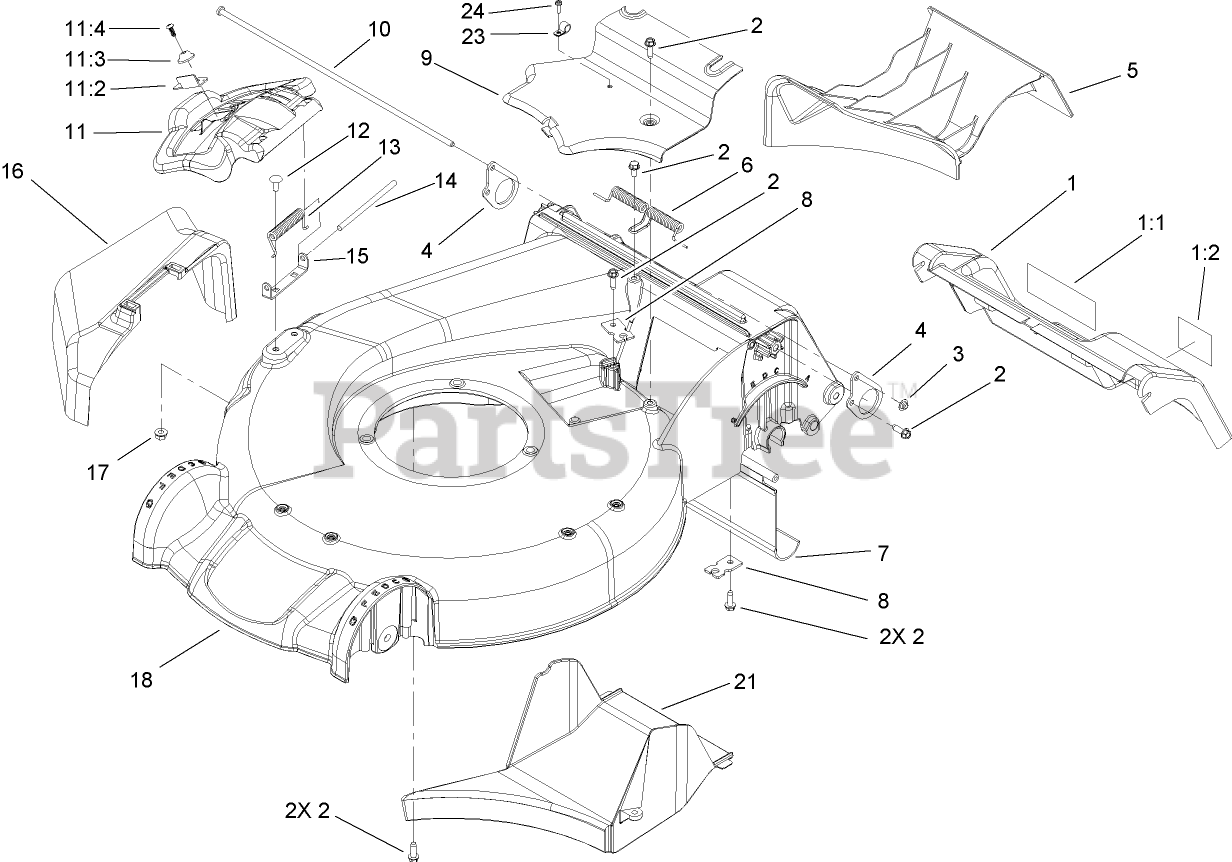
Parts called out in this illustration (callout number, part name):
1	DOOR-SERVICE
1:1	DECAL-WARNING
1:2	DECAL-WARNING
2	SCREW-HWHTF
3	NUT-SPEED
4	PLATE-SUPPORT, DOOR
5	MULCH PLUG ASM
6	Spring-Door, Rear
7	SHIELD-TRAILING
8	BRACKET-CABLE, TRACTION
9	COVER-BELT
10	ROD-SUPPORT, DOOR
11	DISCHARGE DOOR ASM
11:2	LATCH-DOOR
11:3	CAP-DOOR
11:4	SCREW-PLASTITE
12	SCREW-CARR
13	SPRING-TORSION
14	ROD-COVER
15	BRACKET-COVER
16	CHUTE-DISCHARGE, SIDE
17	NUT-HHF
18	HOUSING ASM
21	TUNNEL-DISCHARGE
23	CLAMP
